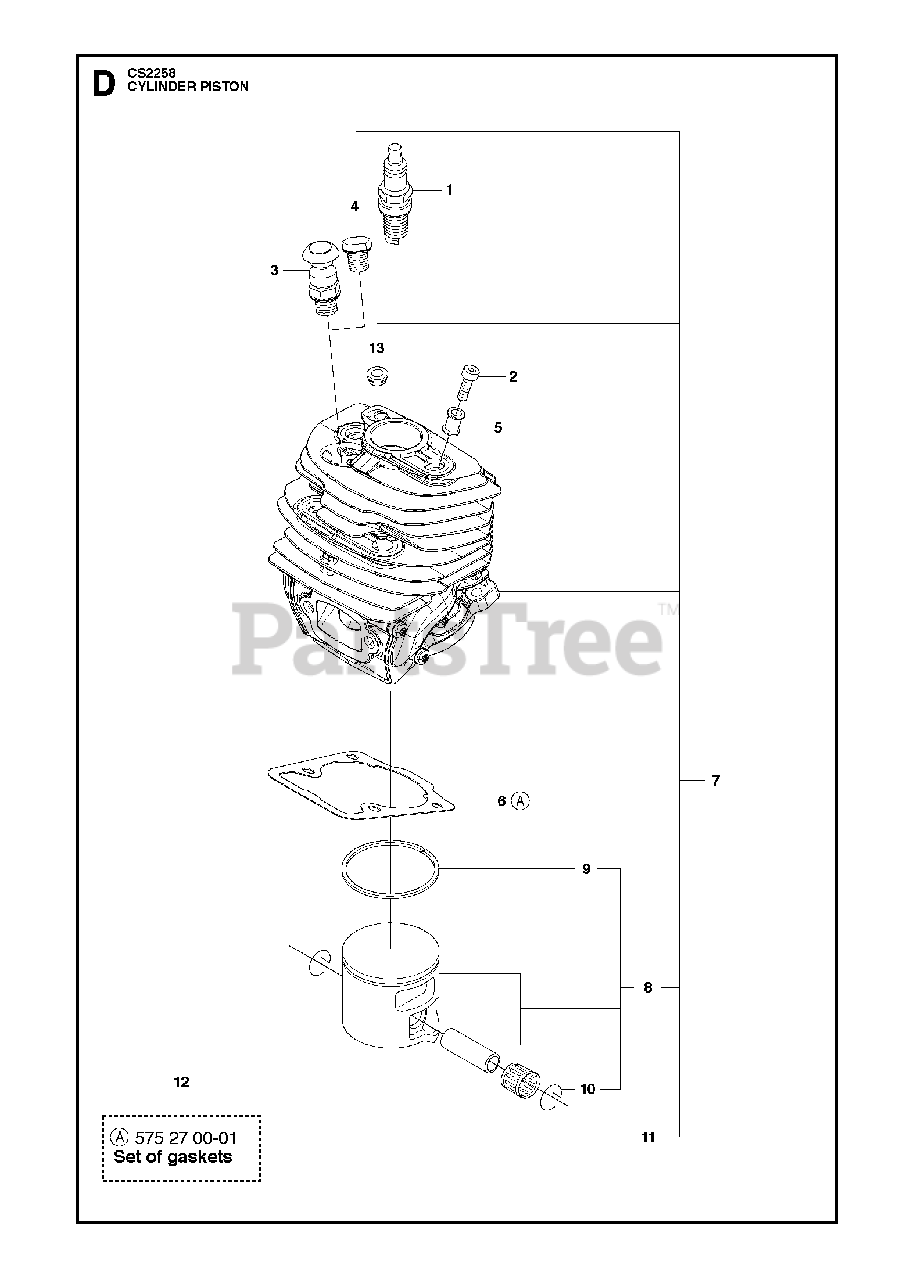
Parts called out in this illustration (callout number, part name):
1	CMR6H SPARK PLUG NGK
2	SCREW MC6S 5X35
3	DECOMPRESSION VALVE
4	CYLINDER PLUG
6	GASKET
7	CYLINDER-PISTON ASSY
8	PISTON ASSY
9	PISTON RING
10	LOCKING RING
11	NEEDLE BEARING
12	RP GASKET KIT
13	BUSHING
